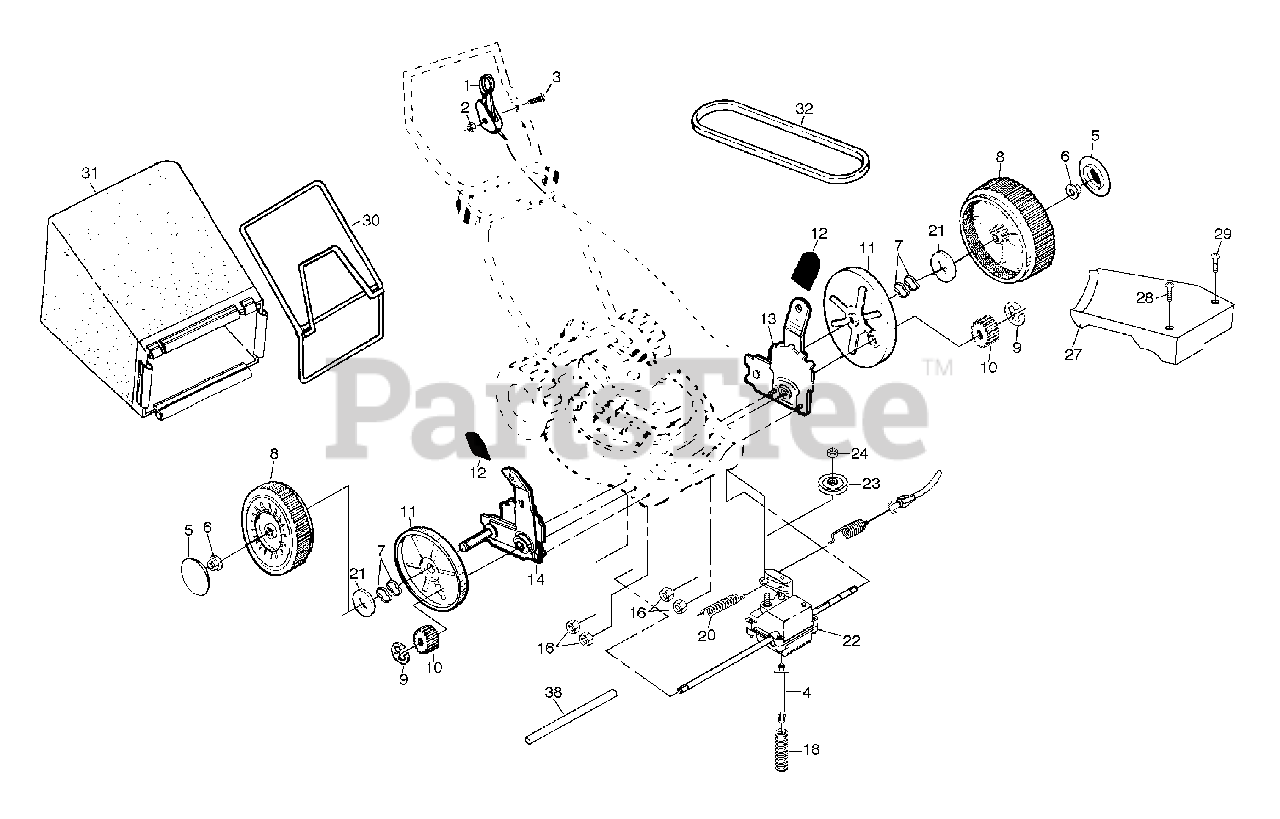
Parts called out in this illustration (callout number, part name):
1	Drive Control
2	Locknut #10-24
3	Pan Head Machine Screw 1/4-20 x 2-1/8
4	Spring Retainer
6	Nut
7	Wave Washer
8	Wheel & Tire Assembly
11	Dust Cover
12	Selector Knob
13	Wheel Adjuster Assembly (Left)
14	Wheel Adjuster Assembly (Right)
16	Locknut
21	Washer 1/2 x 1-1/2 x .134
22	Gear Case Assembly
23	Drive Pulley
24	Locknut
27	Drive Cover
29	Pan Head Tapping Screw #10-24 x 1-3/4
30	Catcher Frame
31	Grass Bag
32	V-Belt
38	Drive Shaft Cover
